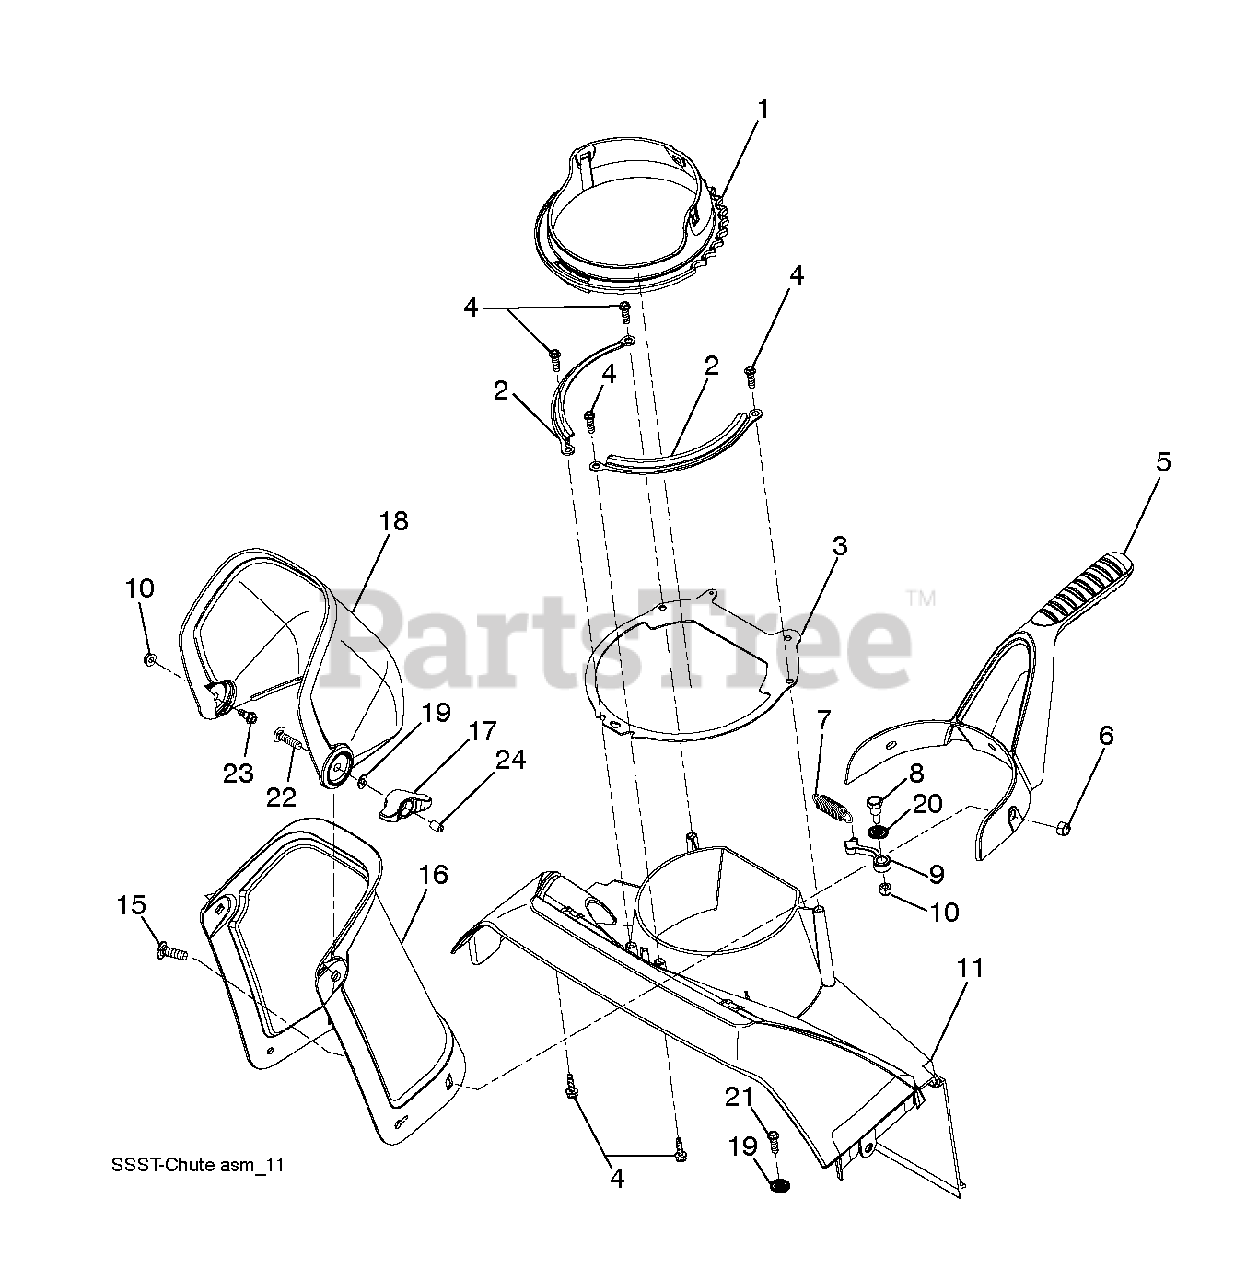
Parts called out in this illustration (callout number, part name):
1	CHUTE.RATCHETING.PLASTIC.W/GRV
2	PLATE.CHUTE.RETAINER
3	PLATE.CHUTE.BASE
4	SCREW.HX.13X.750
5	HANDLE.CHUTE.BLACK
6	LOCKNUT-FLANGE 5/16-18
7	SPRING.RATCHET.ARM
8	SHOULDER BOLT ST
9	ARM.CHUTE.RATCHET
10	NUT
11	PLENIUM.AUGER.POULAN PRO.BLACK
15	BOLT.CARR.5/16-18X1.BLACK
16	CHUTE.SINGLE.STAGE.SNOW.BLACK
18	DEFLECTOR.CHUTE.BLACK
20	WASHER.13/32X1-1/2X16GA
21	BOLT.HEX.HD.WASHER.5/16-18X.75
22	BOLT.CARRIAGE.5/16-18
23	BOLT.SHOULDER.HEX.HD.1/4-20
24	PLUNGER CAP
